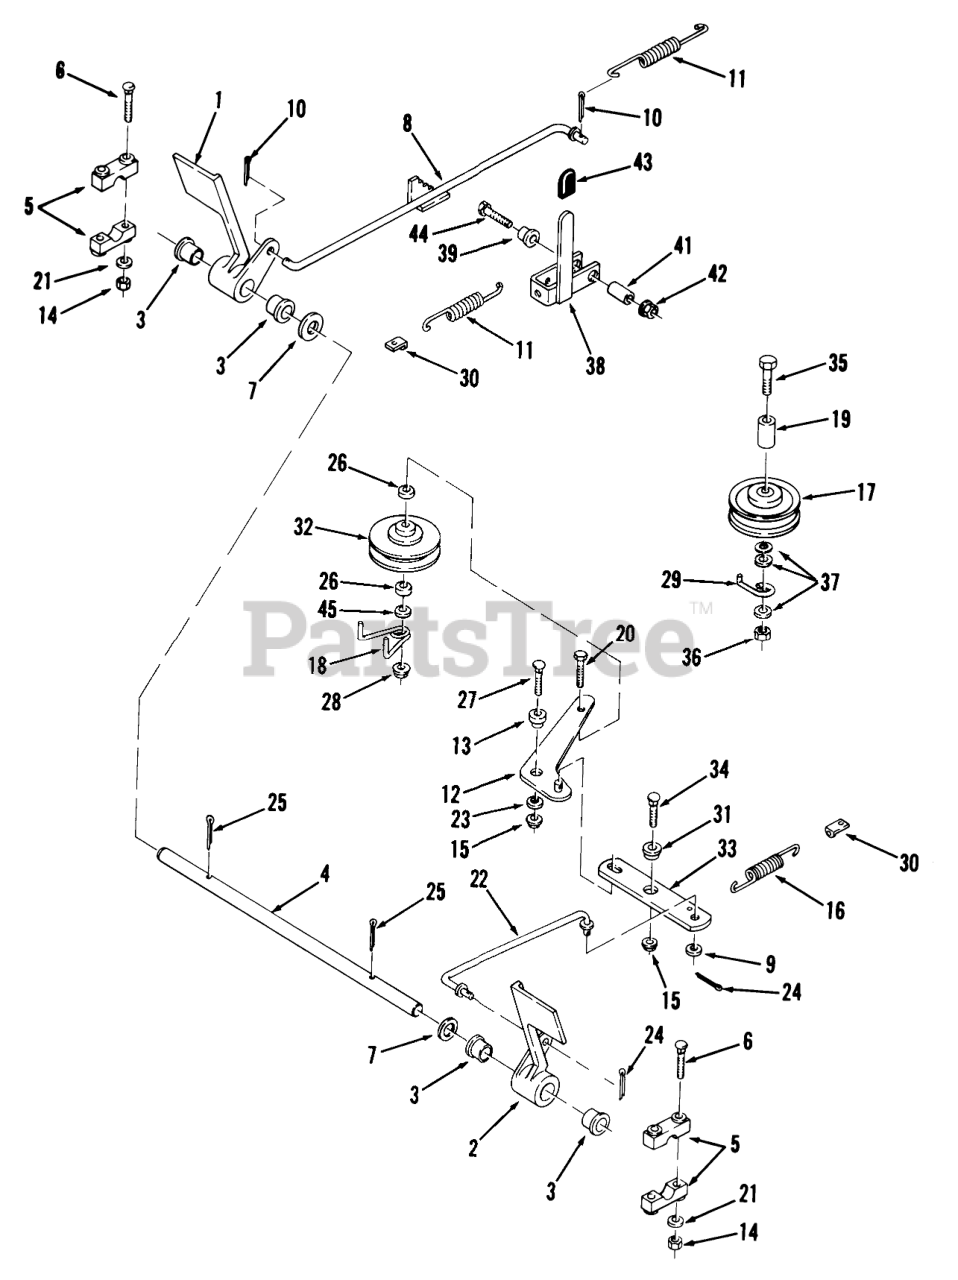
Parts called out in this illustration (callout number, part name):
1	Pedal-Brake (Includes Item 3)
2	Pedal-Clutch (Includes Item 3)
3	BEARING
4	Shaft-Pedal
5	BLOCK PIVOT
6	Washer
7	Washer
8	Assy Brake Rod
9	WASHER 5/16 SAE
10	Pop Rivet
11	SPRING-EXTENSION
12	IDLER ARM ASSY R
13	SPACER-IDLER ARM
14	Nut
15	LOCKNUT-FLANGE
16	SPRING
17	PULLEY-IDLER STATION
18	BELT GUIDE
19	SPACER
20	Bolt
21	WASHER 5/16 SAE
22	ROD-CLUTCH R
23	Washer
24	Pop Rivet
26	SPACER
27	Carriage Bolt
28	LOCKNUT-FLANGE
29	RETAINER-BELT
30	CLIP - SPRING
31	SPACER
32	Pully-Idler
33	BAR-CLUTCH
34	Bolt
35	Bolt 3/8-16 x 3 1/4
36	Nut
37	Washer
38	PAWL-HANDLE ASSY
39	SPACER
41	SPACER
42	LOCKNUT-FLANGE
43	GRIP
44	Bolt
45	Washer
